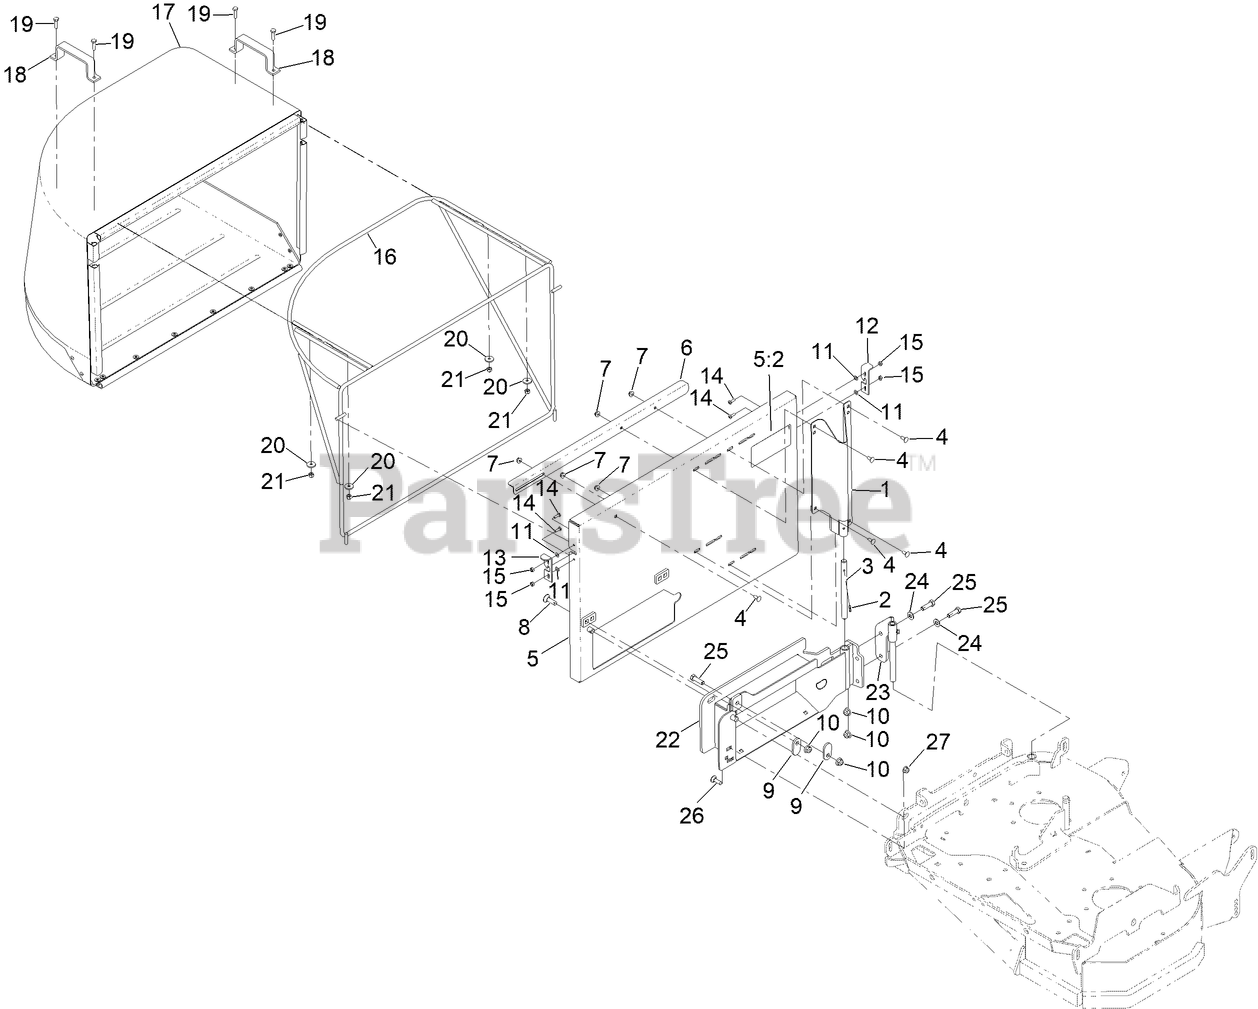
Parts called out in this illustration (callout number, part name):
1	WLD-BAG SUPT CHANNEL
2	PIN-ROLL
3	SHAFT-CATCHER, GRASS
4	SCREW-CARR
5	SIDE BAG PLATE W/DECAL
5:2	DECAL-WARNING THROWN OBJECTS
6	BAFFLE,ANTI-BLOWOUT
7	NUT-HF
8	BOLT-CARR
9	LATCH-CATCHER, GRASS
10	NUT-HF, NI
11	WASHER-SPRING
12	LATCH-CATCHER, RH
13	LATCH-CATCHER, LH
14	SCREW-PPH
15	NUT-LOCK, NI
16	FRAME-CATCHER
17	PAN AND CATCHER
19	SCREW-HH
20	WASHER
21	NUT-LOCK, NI
22	WELD-ADAPTOR ACC.
23	ASM-ADAPTOR HANGER
24	WASHER-FLAT
25	SCREW-HH
26	BOLT-CARR
27	NUT-HF, NI
